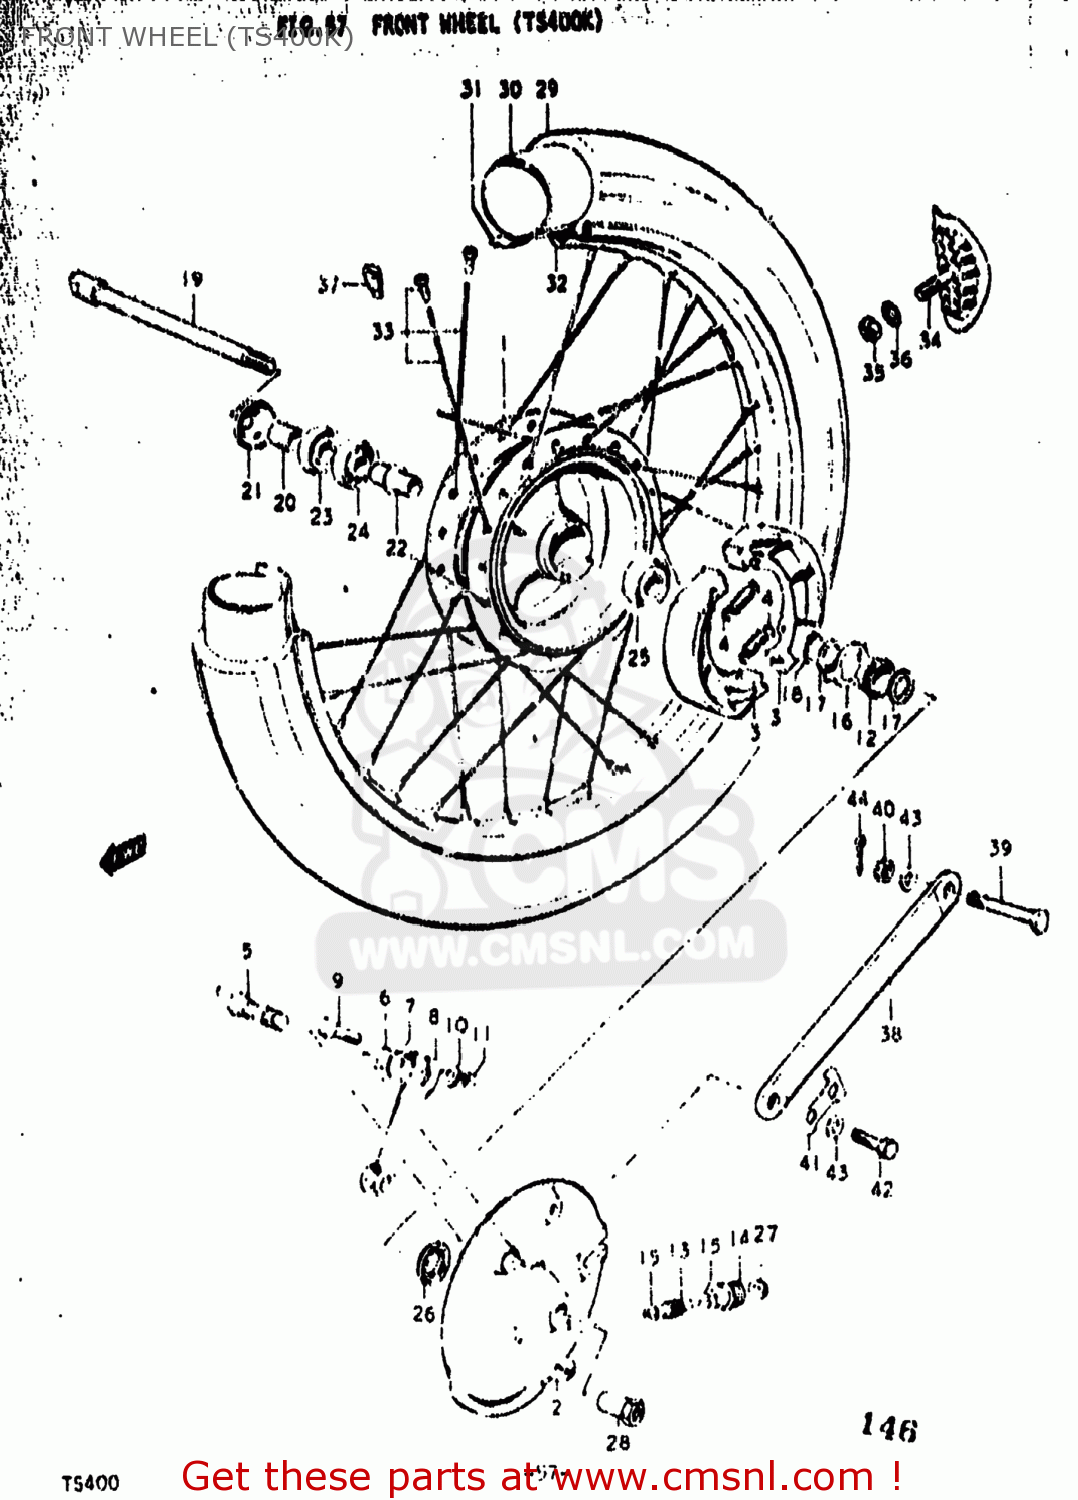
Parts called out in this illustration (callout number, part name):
1	HUB,FRONT
2	PANEL,FRONT HUB
3	SHOE,BRAKE
4	SPRING,BRAKE SHOE
5	CAM,FRONT BRAKE
6	O-RING,BOSS
7	WASHER (15X24X1.6)
8	LEVER,FRONT BRAKE CAM
9	BOLT
10	WASHER
11	NUT
12	GEAR,SPEEDOMETER
13	PINION,SPEEDOMETER
14	BUSHING,SPEEDOMETER PINION
15	WASHER (5.1X9X0.4)
16	DRIVER,SPEEDOMETER GEAR
17	WASHER(22.5X27X1)
18	CIRCLIP
19	AXLE,FRONT
20	SPACER
21	DUST SEAL,FRONT HUB DRUM
22	SPACER,FRONT HUB BEARING
23	OIL SEAL
24	BEARING
25	BEARING
26	OIL SEAL
27	SEAL,OIL(6X10X3)
28	NUT,FRONT AXLE
29	TIRE,FRONT
30	TUBE,INNER
31	PROTECTOR,WHL INR TUBE
32	RIM,FRONT WHEEL
33	SPOKE SET,FRONT
34	STOPPER,BEAD
35	NUT
36	WASHER
37	BALANCER,WHEEL (50G)
39	BOLT
40	NUT 8MM
41	MUD FLAP,FRONT FENDER,LEFT
42	BOLT(8X19.5)
43	WASHER
44	PIN
